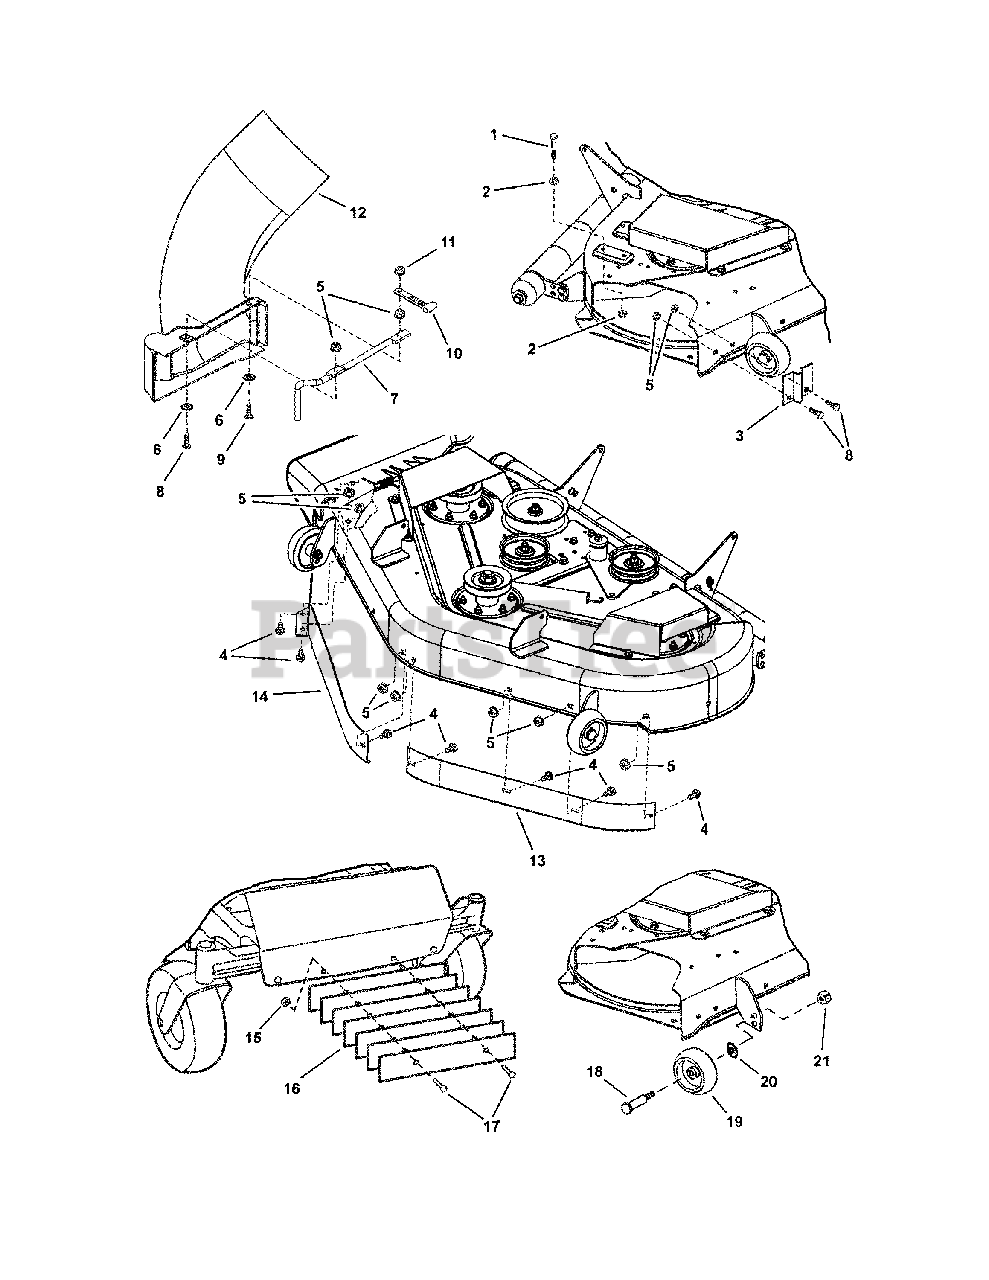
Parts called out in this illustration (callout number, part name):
1	SCREW, Hex Head Cap, 1/4 - 20 x 2-1/4
2	NUT, Hex Flange, 1/4 - 20
3	PLATE, Rod Mount
4	BOLT, Carriage, 5/16 - 18 x 5/8
5	NUT, Flange, 5/16 - 18
6	WASHER, SAE, 5/16
7	ROD, Adapter Mount
8	SCREW, Hex Head Cap, 5/16 - 18 x 3/4
9	BOLT, Hex Flange, 5/16 - 18 x 1-1/2
10	STRAP, Rubber
11	NUT, Hex Lock, 5/16 - 18
12	ADAPTER, Bag
13	BAFFLE, L.H. 44" Mower Deck
13	BAFFLE, L.H. 50" Mower Deck
14	BAFFLE, R.H. 44" Mower Deck
14	BAFFLE, R.H. 50" Mower Deck
15	NUT, Hex Center Lock, 5/16 - 18
17	BOLT, Carriage, 5/16 - 18 x 2-1/2
18	WHEEL, Gauge
19	BOLT, Shoulder
20	WASHER, SAE, 3/8
21	NUT, Hex Center Lock, 3/8 - 16
